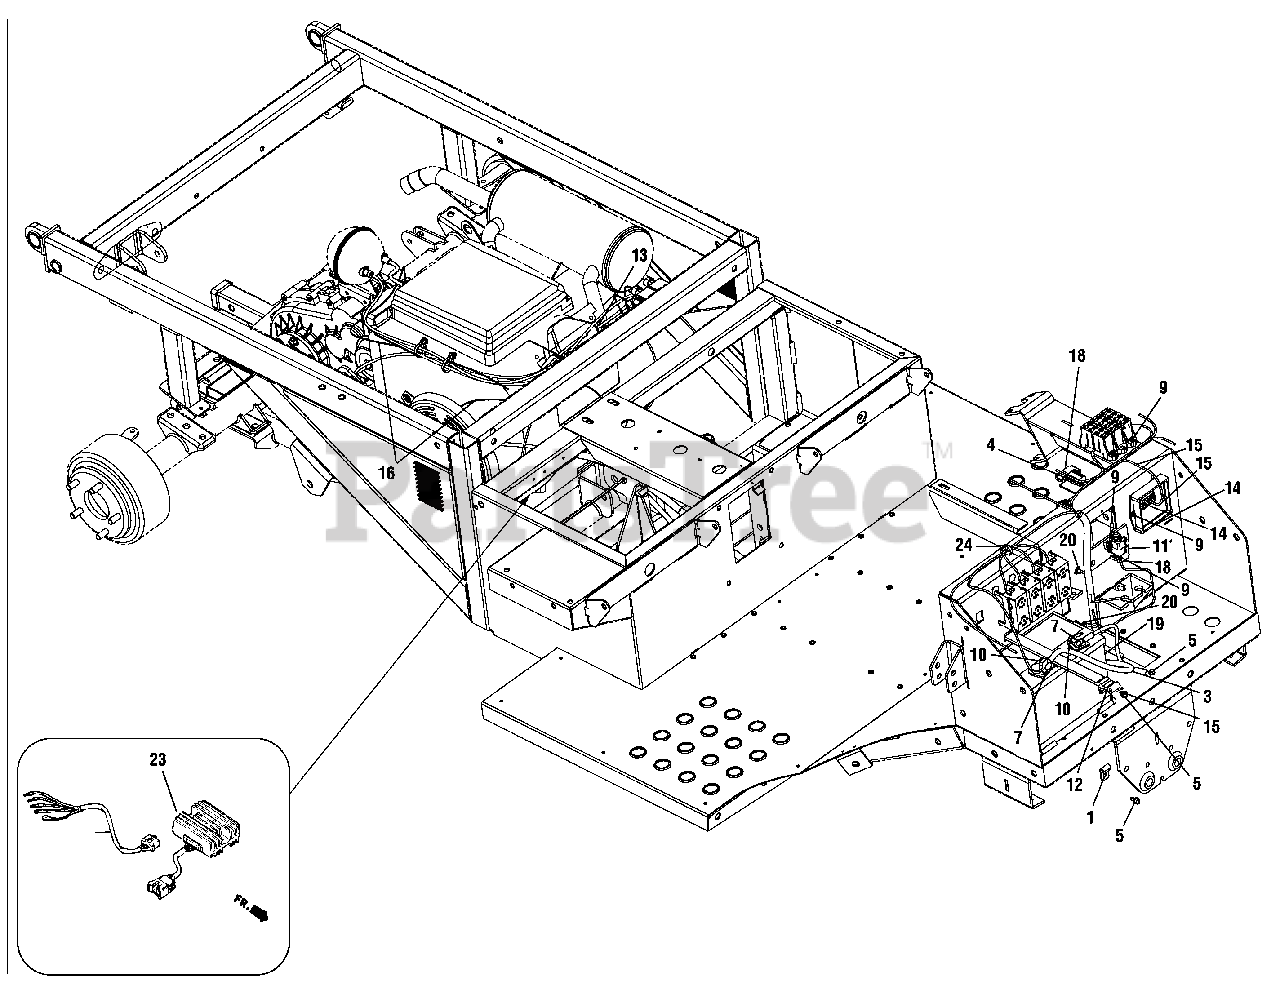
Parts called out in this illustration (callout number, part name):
1	Bracket, Retainer Hook
3	Harness Assembly, Motor Ground
4	Screw, 1/4-20 x .50
5	Screw, Self-tapping, 1/4-20 x 0.500
7	Screw, Hex Carriage, 1/4-20 x .75
9	Screw, #10-24 x 0.75
10	Nut, Hex Sems, 1/4-20
11	Cover, Protective
12	Strap, Battery
13	Cable Tie, 3/16 x .05 x 7.4
14	Control, Shaft
15	Harness, Utility Main
16	Harness, Motor
18	Switch
19	Battery
20	Cable Tie, .19 x 8.39 Tree Mount
23	Rectifier Assembly, Regulator (20A)
24	Retainer Clip, .250 x .267
